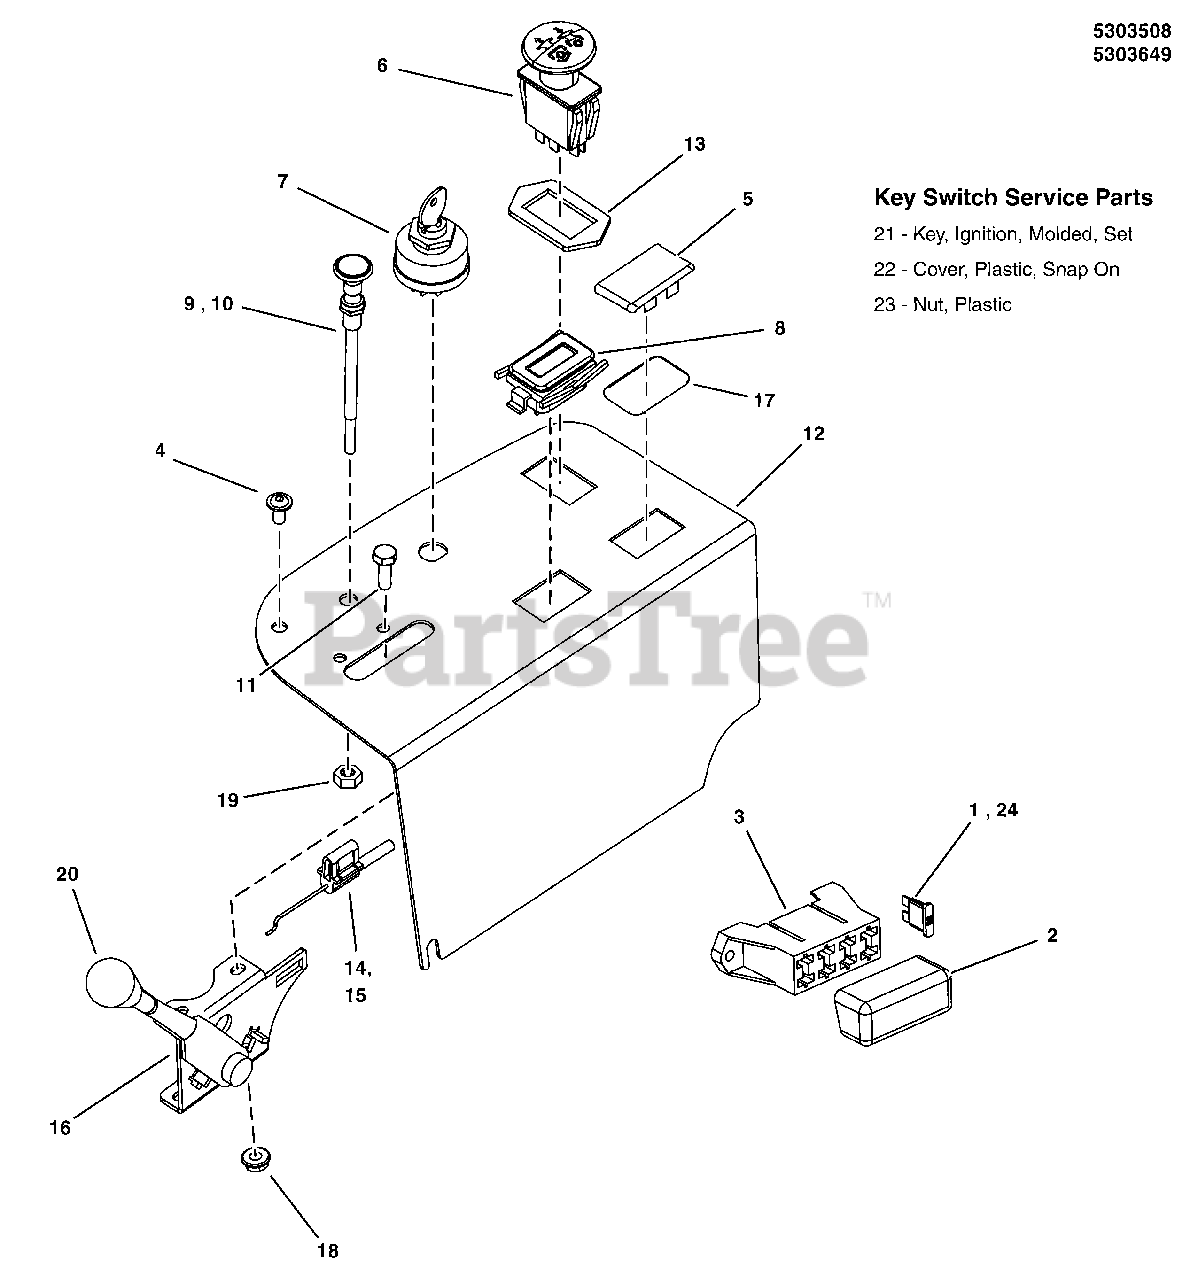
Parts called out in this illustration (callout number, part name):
1	FUSE, ATO, 20 AMP (SV)
2	COVER, VINYL FUSEBLOCK
3	FUSE, BLOCK
4	SCREW, ALLEN HEAD 1/4-20 X .500 ZINC PHOS
5	PLUG, Hole, Electric Lift (Hydro models only)
6	SWITCH, Blade Engage
7	SWITCH, IGNITION, 6 POST
8	HOUR METER, ASSEMBLE
9	CABLE, Choke
10	CABLE, CHOKE CONTROL, 51 (Z)
11	SCREW, #10-24 X 3/4", ROUND PHILLIPS
12	PANEL, CONTROL, IS2100Z - BLK
13	RING, SWITCH RETAINER, PTO
14	CABLE, THROTTLE, 42"
15	CABLE, THROTTLE, 47"
16	LEVER, THROTTLE CONTROL, HEAVY DUTY
17	O-RING, 7/8" ID X 1/16" W
18	NUT, Nylock, #10-24, GR2
19	NUT, 3/8 - 24 HEX
20	THROTTLE CONTROL HANDLE/KNOB
21	KEY, IGNITION MOLDED SET (SV)
22	COVER, PLASTIC, SNAP ON (SV)
23	NUT, PLASTIC (SV)
24	FUSE, ATO, 15 AMP (SV)
